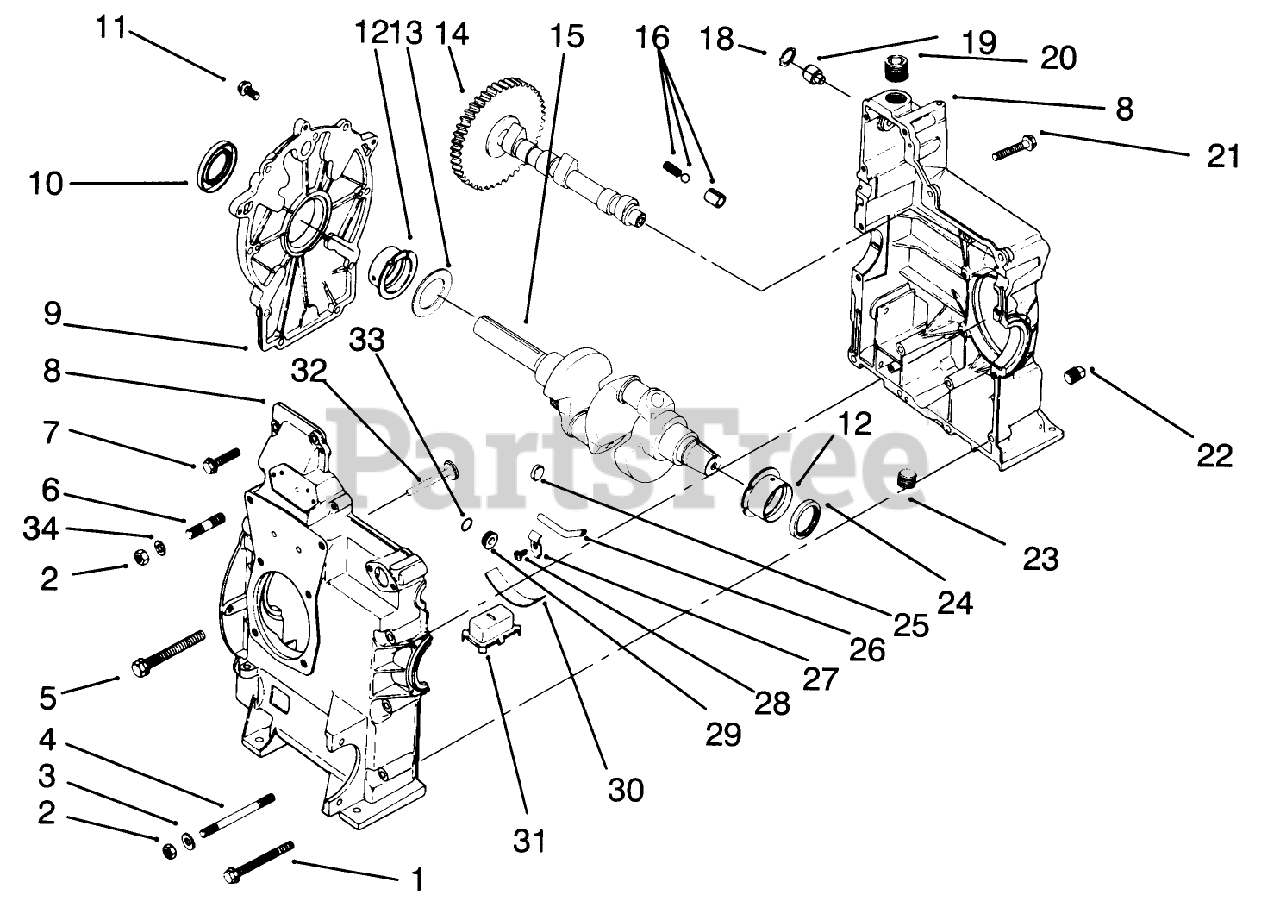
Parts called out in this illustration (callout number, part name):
1	Screw-Hex Flange
2	Nut
3	Washer-Flat
4	Stud
5	Screw-Hex Flange
7	Screw-Hex Flange
8	Cranckcase (Service With Shortblock
9	Kit-Closure Plate (Incl. Ref. #10)
10	Seal-RearOil
11	Screw-Wash Head
12	Bearing-Sleeve .020"
13	Washer-Thrust
14	Camshaft
15	Crankshaft
16	Kit-Oil Relief
18	Ring-Retaining
19	Shaft-Governor
20	Plug
21	Screw-Hex Flange
22	Plug
23	Plug-Hex
24	Seal-ReAR Oil
25	Plug-Cup
26	Tube-Oil Pickup
28	Screw
30	Clip-Spring
31	Housing-Oil
34	Washer-Flat
